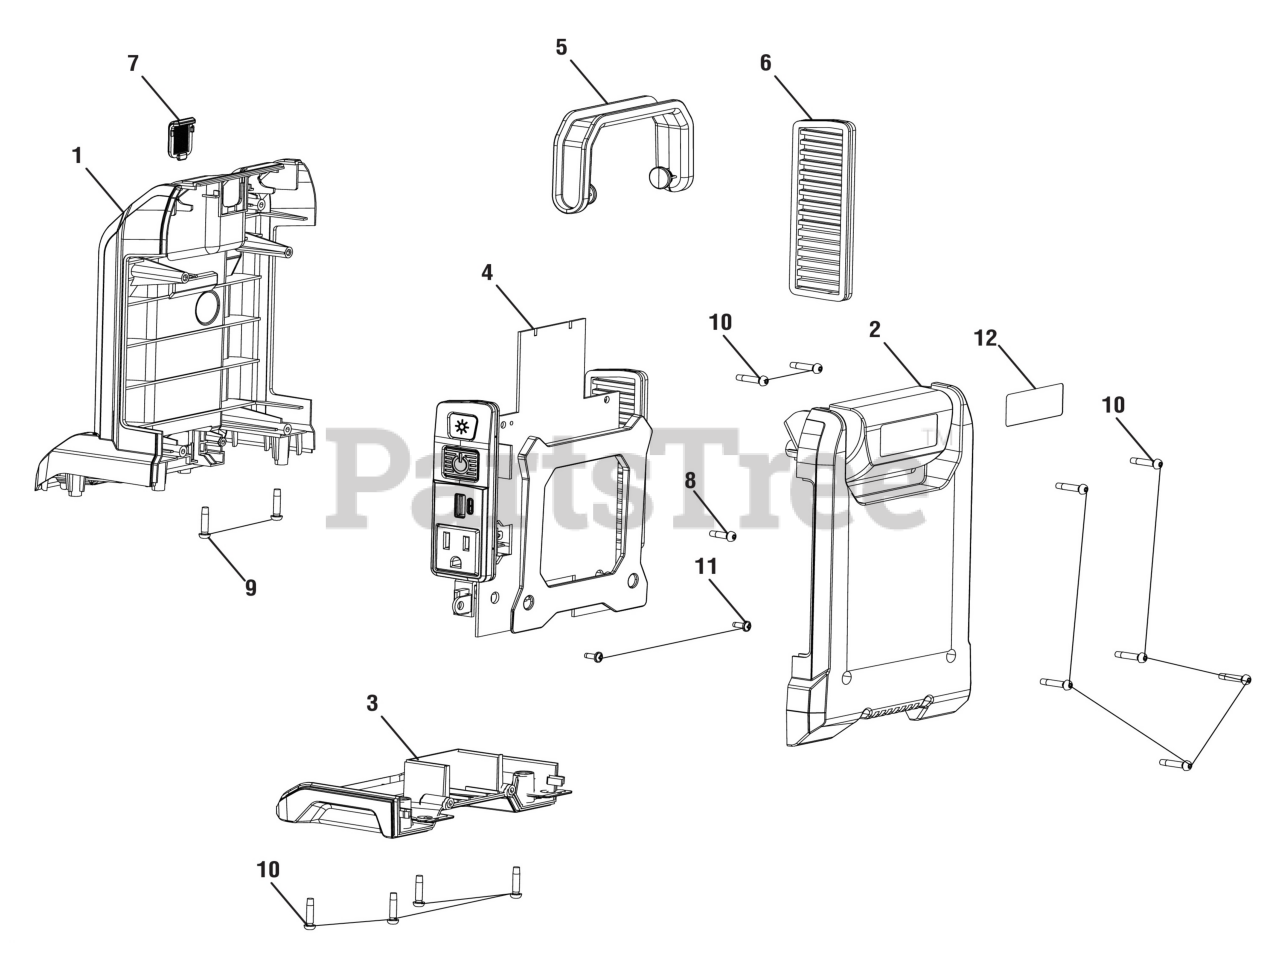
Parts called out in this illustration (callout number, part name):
1	Upper Housing
2	Back Housing Assembly (Inc. Key No. 12)
3	Back Housing
4	Control Panel Assembly
6	Side Panel Vent
7	LED Task Light
8	Screw (M3 x 8 mm, Pan Hd., Pan Hd)
9	Screw (M3 x 8 mm)
10	Screw (M3.5 x 16 mm, T10 Torx Pan Hd.)
11	Screw (M4 x 13.5 mm)
12	Logo Label
